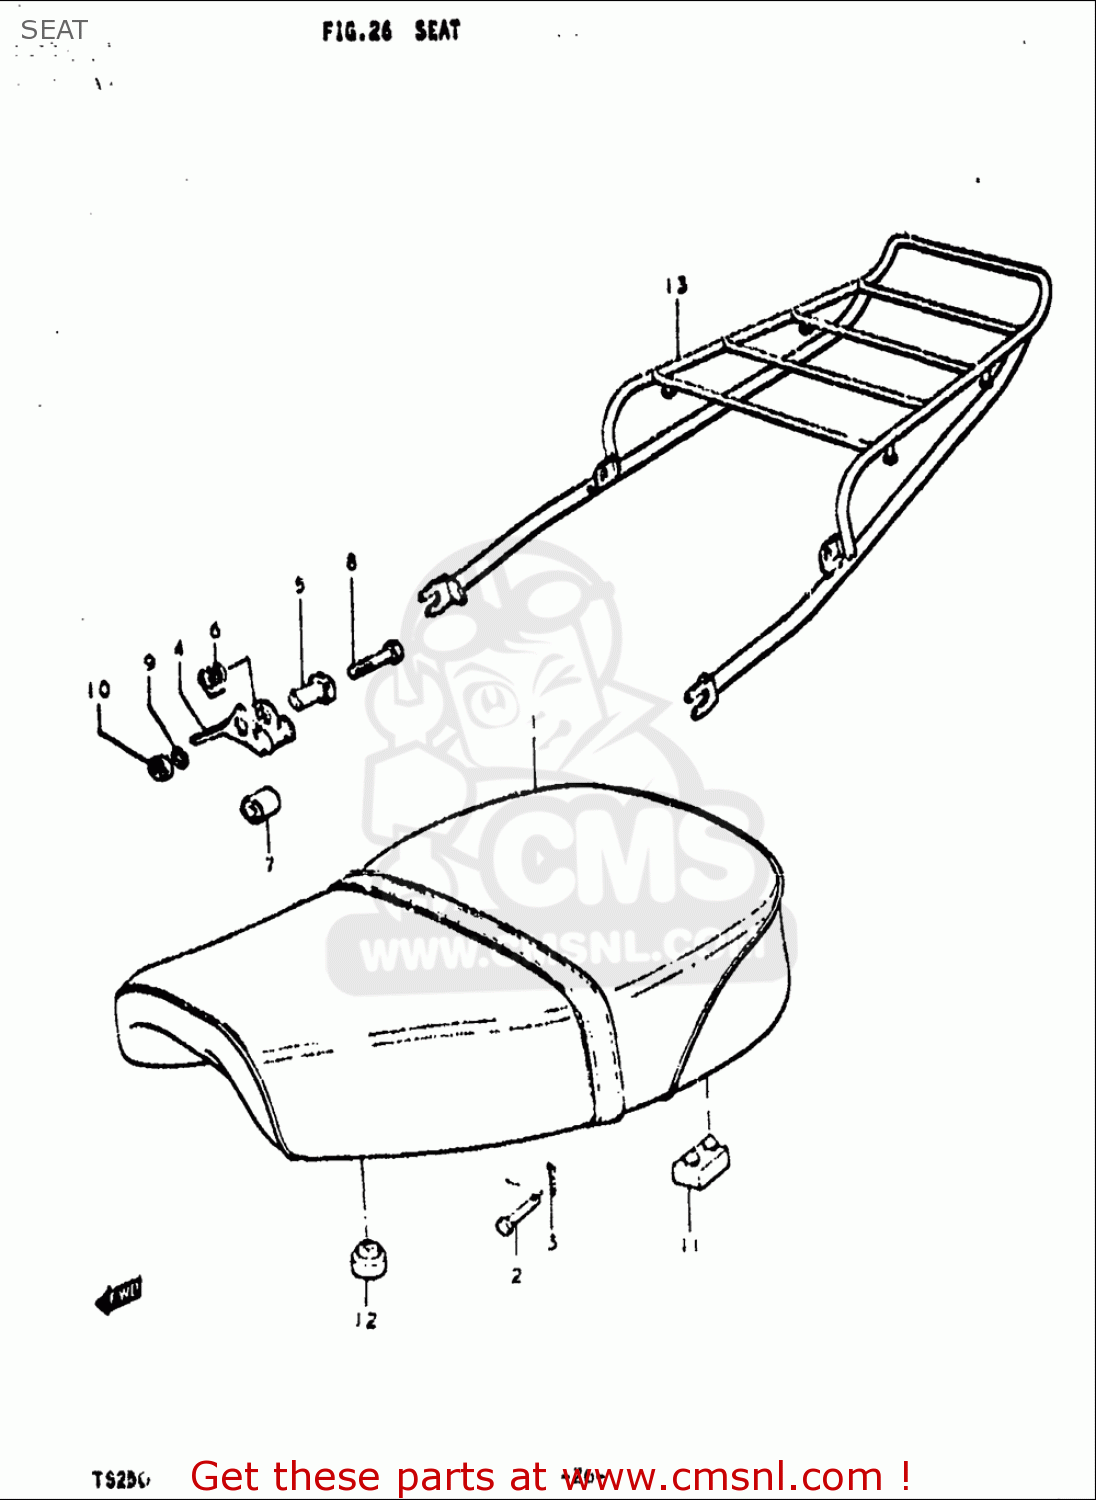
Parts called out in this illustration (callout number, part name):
2	PIN
3	PIN
5	STRIKER,SEAT LOCK
6	SPRING
7	BUSHING
8	BOLT
9	WASHER,LOCK
10	NUT
11	CUSHION
12	CUSHION(11.5X22X20)
